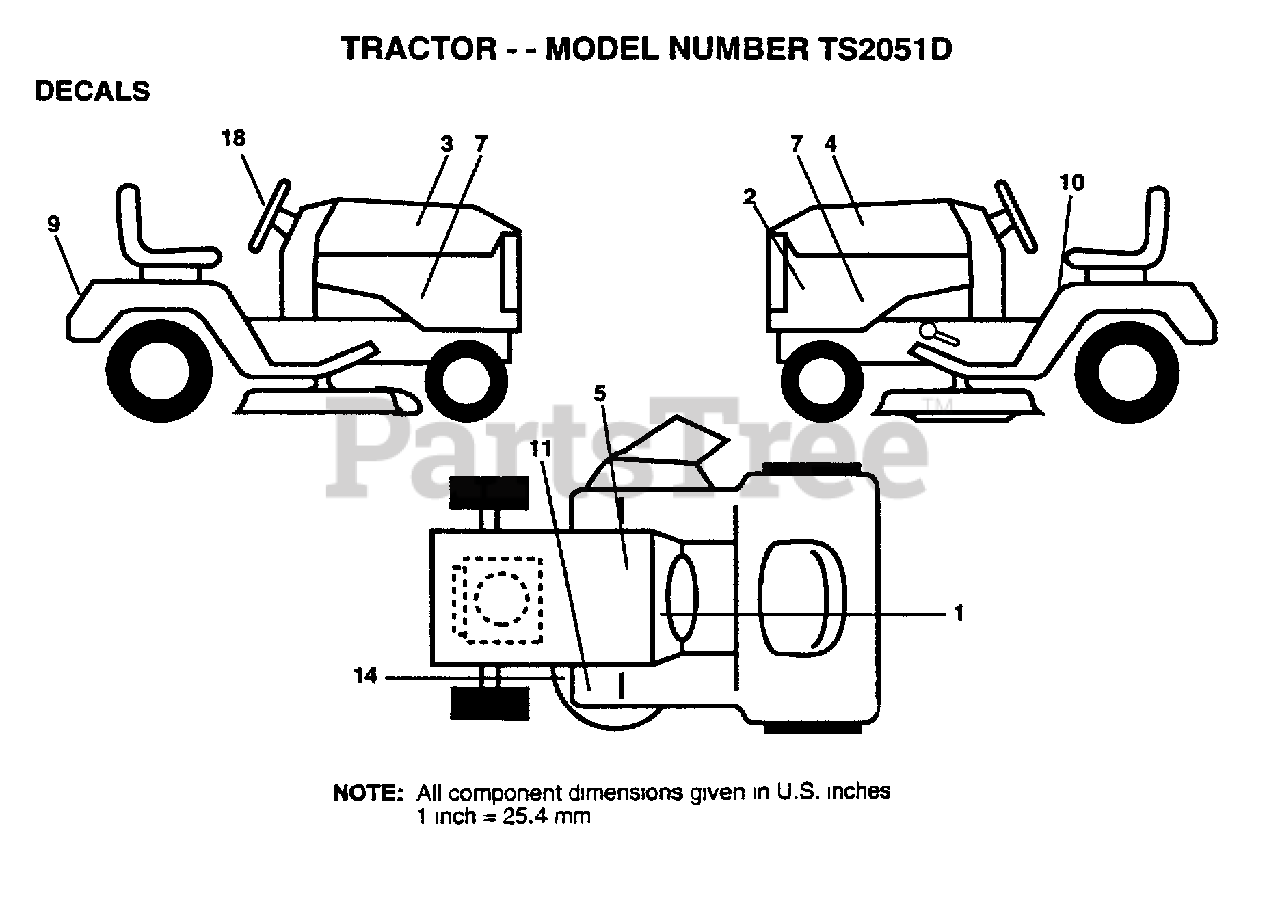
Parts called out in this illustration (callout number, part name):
1	DECAL.DASH.INST.
2	NAMEPLATE.HUSK.LG
3	DECAL.HD.RH.20/50
4	DECAL.HD.LH.20/50
5	DECAL.BATRY.3-3908
7	DECAL.PNL.SIDE.20
9	DECAL.FEND.YT/GT
10	DECAL
14	"DECAL.V.BELT.44"""
18	DECAL.INS.WHL.STG
